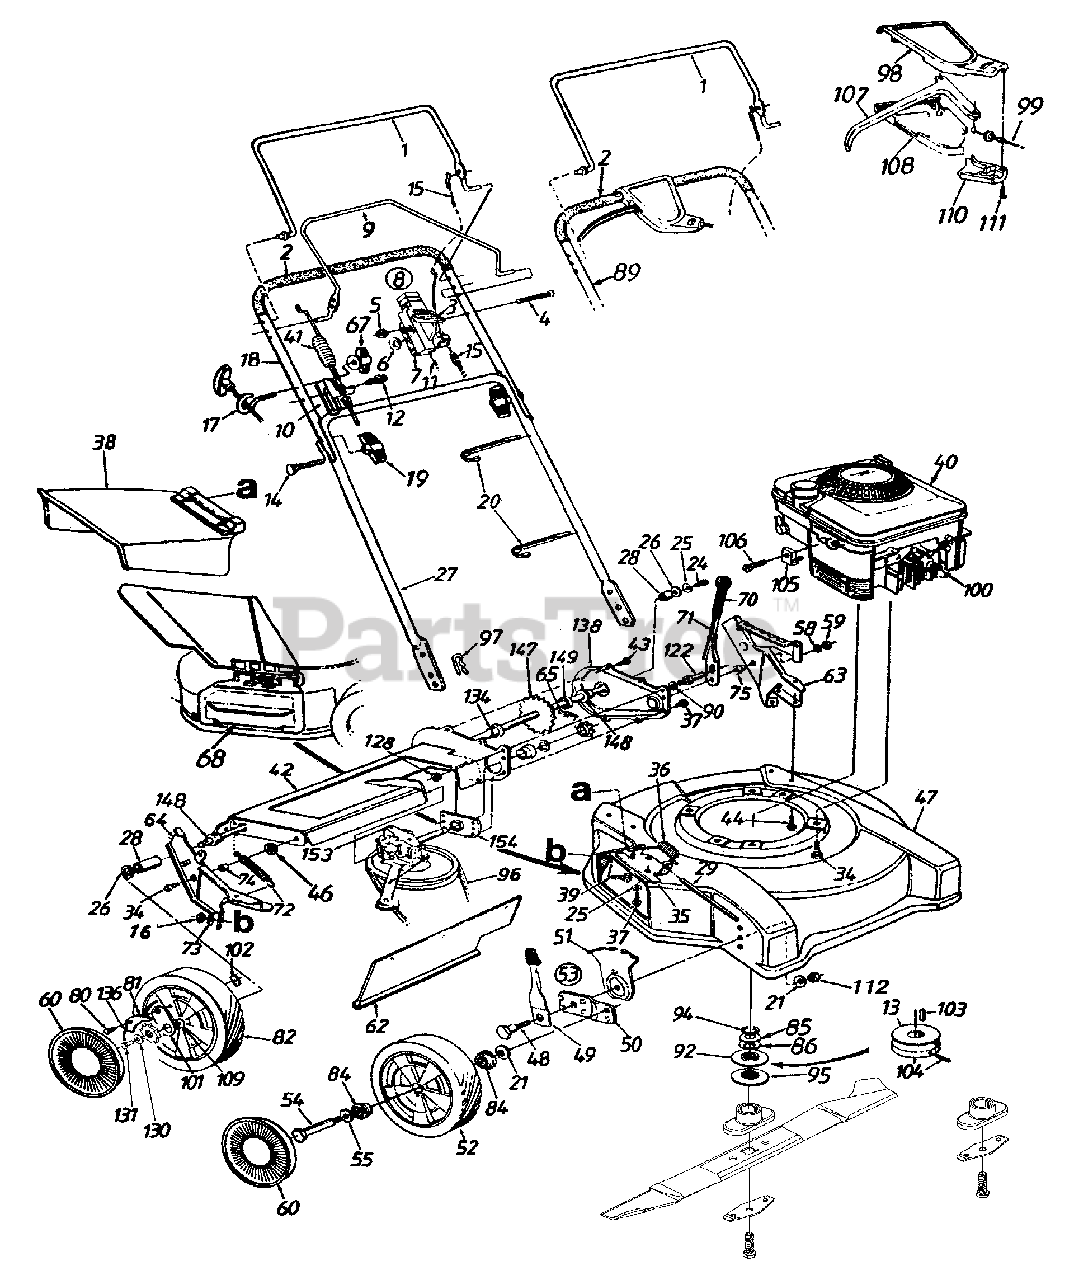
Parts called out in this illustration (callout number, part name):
2	Foam Grip
3	Throttle Lever
4	Oval C-Sunk Scr.
5	Hex L-Nut 1/4-20 Thd.
6	Spr. Wash. .66" I.D.
7	Throttle Body
8	Throttle Box Comp.
11	Throttle Cable 55" Lg.
12	Hex Wash. AB-Tap Scr. 5/16 x .75" Lg.
13	Keyed Pulley
14	Curved Hd. Bolt 5/16-18 x 2"
15	Control Cable 39" Lg.
16	L-Wash. 5/16" I.D.
17	Rope Guide
20	Cable Tie
21	Bell-Wash. .38" I.D. x .88"
24	Hex Bolt 1/4-20 x .62" Lg.(Grade 5)
25	Bell-Wash. 1/4" I.D.
26	Fl-Wash. .531" I.D. x .93"
28	Spacer .513" I.D. x .703"
29	Hinge Pin
34	Hex L-Wash. Hd. Scr. 3/8-16
35	Adapter Plate
36	Torsion Spring
37	Hex Self-Tap Scr. 1/4-20 x .5"
38	Chute Deflector Ass'y.
39	Carriage Bolt 5/16-18 x .62" Lg.
40	Engine
41	Drive Cable-41.5" Lg. (Dual Bail)
44	Hex Wash. Hd. B-Tap Scr.5/16-18
46	Fl-Wash. .385" I.D. x 1" O.D.
49	Spring Lever Ass'y. w/Knob
51	Height Adj. Plate
52	Wheel Ass'y. Comp.
53	Height Adj. Ass'y. Comp.-R.H.
54	Shld. Bolt .498" Dia. x 1.45"
55	Wave Wash. .51" I.D. x .78"
58	Fl-Wash. .385" I.D. x .87"
59	Hex Patch L-Nut 3/8-24 Thd.
60	Hub Cap, Euro,Grey 3-1/2" Dia.
62	Rear Flap
67	Handle Knob 1/4-20 Thd.
68	Mulching Baffle
71	Height Adj. Lever
72	Ext. Spring .5" O.D. x 3.8" Lg.
73	Bell-Wash. 5/16" I.D.
74	Spacer .383" I.D. x .503"
75	Shld. Spacer .5" Dia.
80	Shld. Scr. .342" Dia. x .268"
81	Pawl-R.H.
82	Wheel Ass'y. Comp.
84	Bearing
85	Spr. Wash. .89 I.D.
86	Fl-Wash. .885 I.D.
90	L-Wash. 3/8" I.D.
92	Upper Pulley Half
94	Crankshaft Spacer
95	Lower Pulley Half
96	"V"-Belt
97	Hairpin Clip
98	Control Cover-Upper Half
99	S.P. Cable (Single Bail)
101	Pawl Plate
102	Weld L-Nut 1/4-20 Thd.
103	Sq. Key, Square, 3/16 x 1/2
104	Set Scr. #10-32 x .25" Lg.
105	Cable Clamp
106	Hex Wash. Hd. Scr. #10-32 x .62" Lg.
107	Control Lever
108	Control Cover-Lower Half
109	Sleeve Brg. 1/2" I.D.
110	Mounting Cap
111	Fl-"C"-Sunk Hd. Tap Scr. #10 x .75" Lg.
112	Bell Wash. .39 I.D. x 1.38 O.D.
122	Shld. Pin 3/8-24 x 1.43" Lg.
128	Hex Jam Nut 3/8-24 Thd.
130	Bell Washer .265 ID x .75
131	Cap Screw HH 1/4-20 x .620
134	Hex Flange Bearing
136	Spring-Nylon
148	Hex Flange Bearing
149	Fl-Wash. .531" I.D. x .93"
153	Transmission Comp
